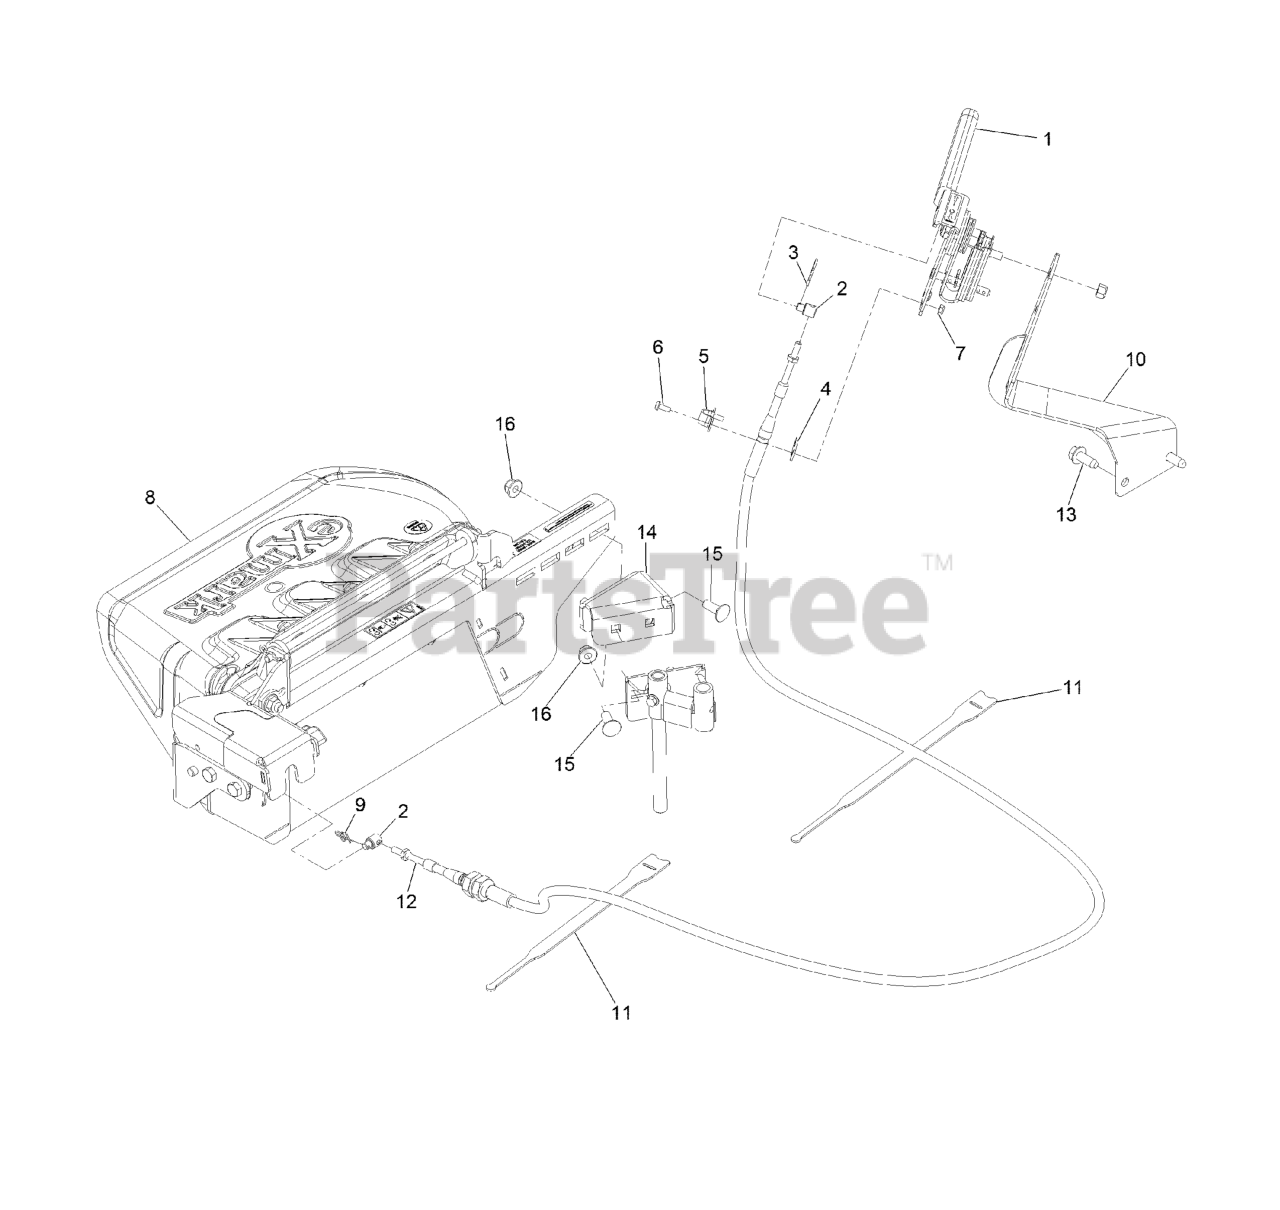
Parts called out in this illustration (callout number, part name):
1	ASM, HAND LEVER
2	PIVOT, CONTROL CABLE
3	PIN-COTTER
4	SHIM,CONTROL CABLE
6	SCREW-PPH
7	NUT-LOCK, NI
8	ASM, OCD
9	PIN-COTTER, LOCKING
10	Mount-Handle Ocdc
11	STRAP-VELCRO, CABLE TIE
12	CABLE-DISCHARGE GATE
13	SCREW-FORMING, THREAD
14	BRACKET-OCD
15	SCREW-CARR
16	NUT-HF, NI
